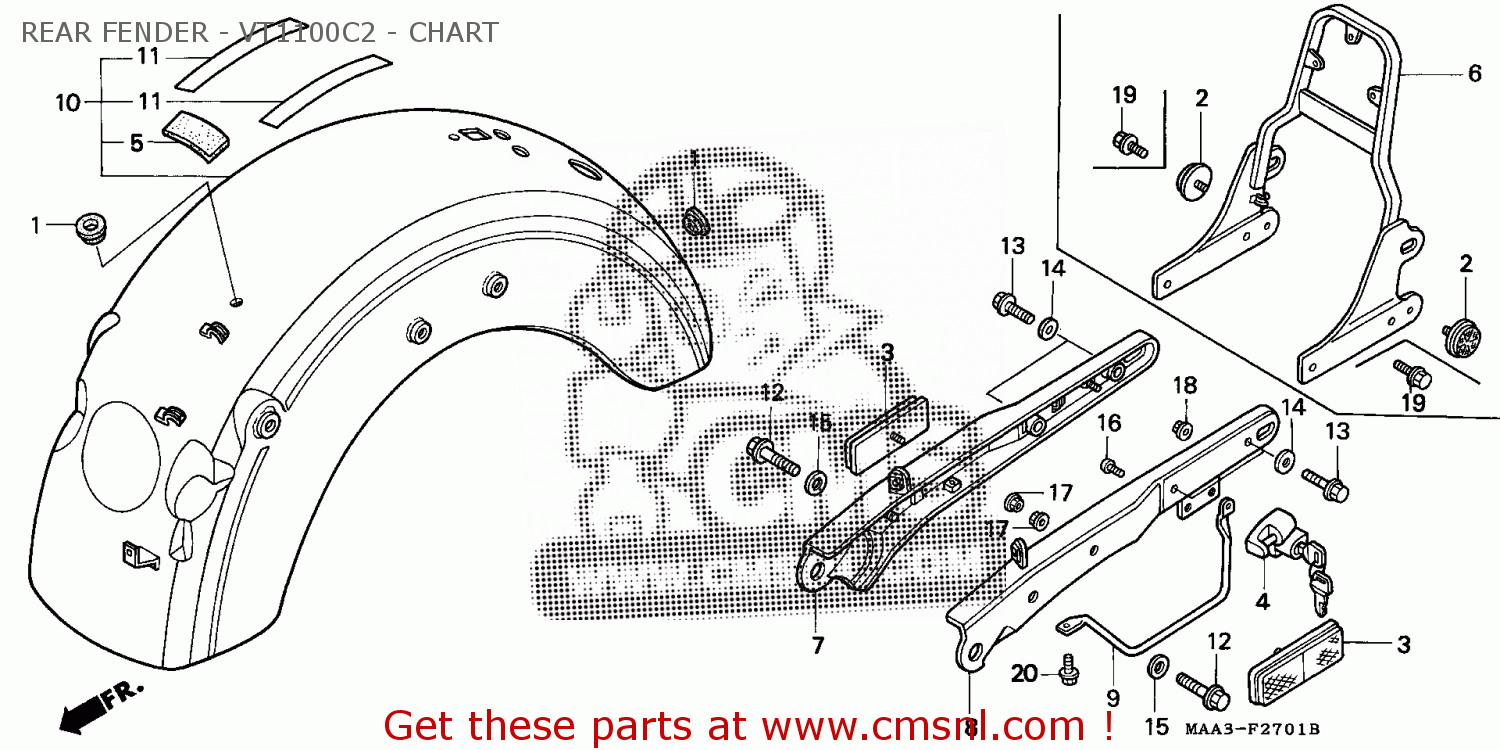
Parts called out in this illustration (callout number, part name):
1	GROMMET,WIRE HORN
4	HOLDER,HELMET
5	PROTECTOR,HOSE
7	RAIL,R GRAB
8	RAIL,L GRAB
9	WIRE,L.GRAB RAIL
10	SET ILLUST*TYPE5*
11	PROTECTOR,REAR FE
12	BOLT,SPECIAL FLAN
13	BOLT,FLANGE,8X26
14	WASHER,PLAIN,8MM
15	WASHER,PLAIN,10MM
16	SCREW,PAN,6X12
18	NUT,FLANGE,6MM
20	BOLT,FLANGE,6X16
